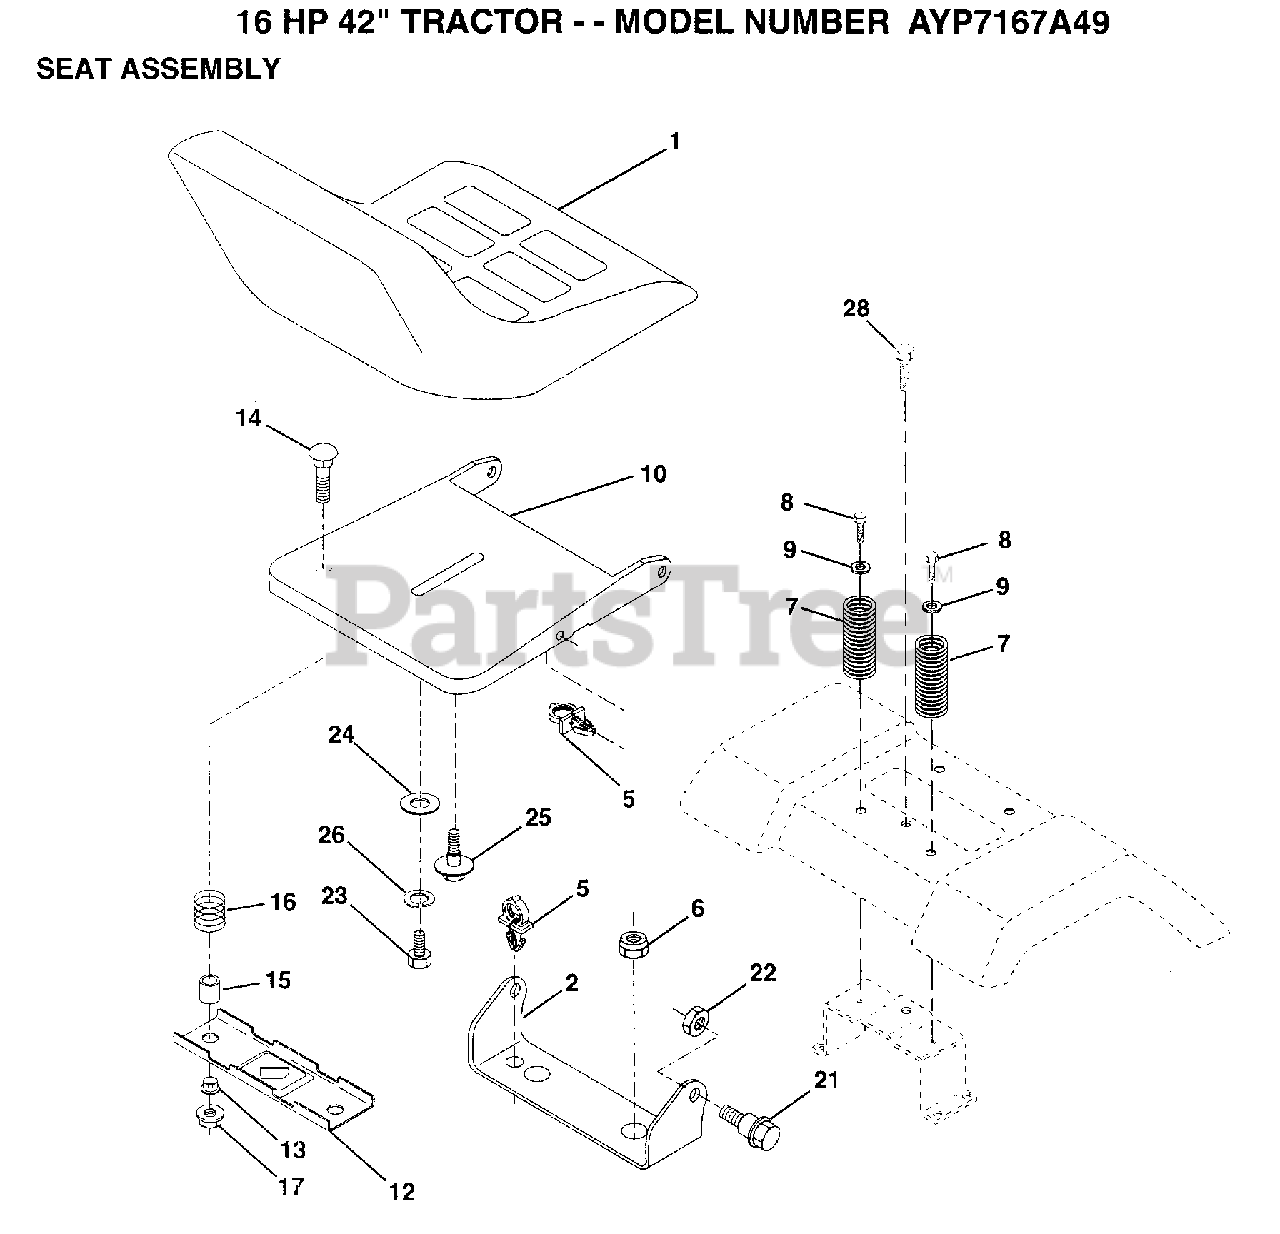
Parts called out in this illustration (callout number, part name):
2	BRACKET PVT SEAT
4	WASHER PM
5	CLIP PUSH - IN
6	NUT
7	SPRING COMPRESSIO
8	SCREW GTV
9	WASHER
11	STRIP FORM
12	BRKT SWITCH
13	BUSHING
15	SPLIT SPACER
16	SPRING
21	BOLT.SHLD.5/16-18
23	BOLT
24	WASHER
25	"BOLT,SHOULDER"
26	LOCKWASHER
